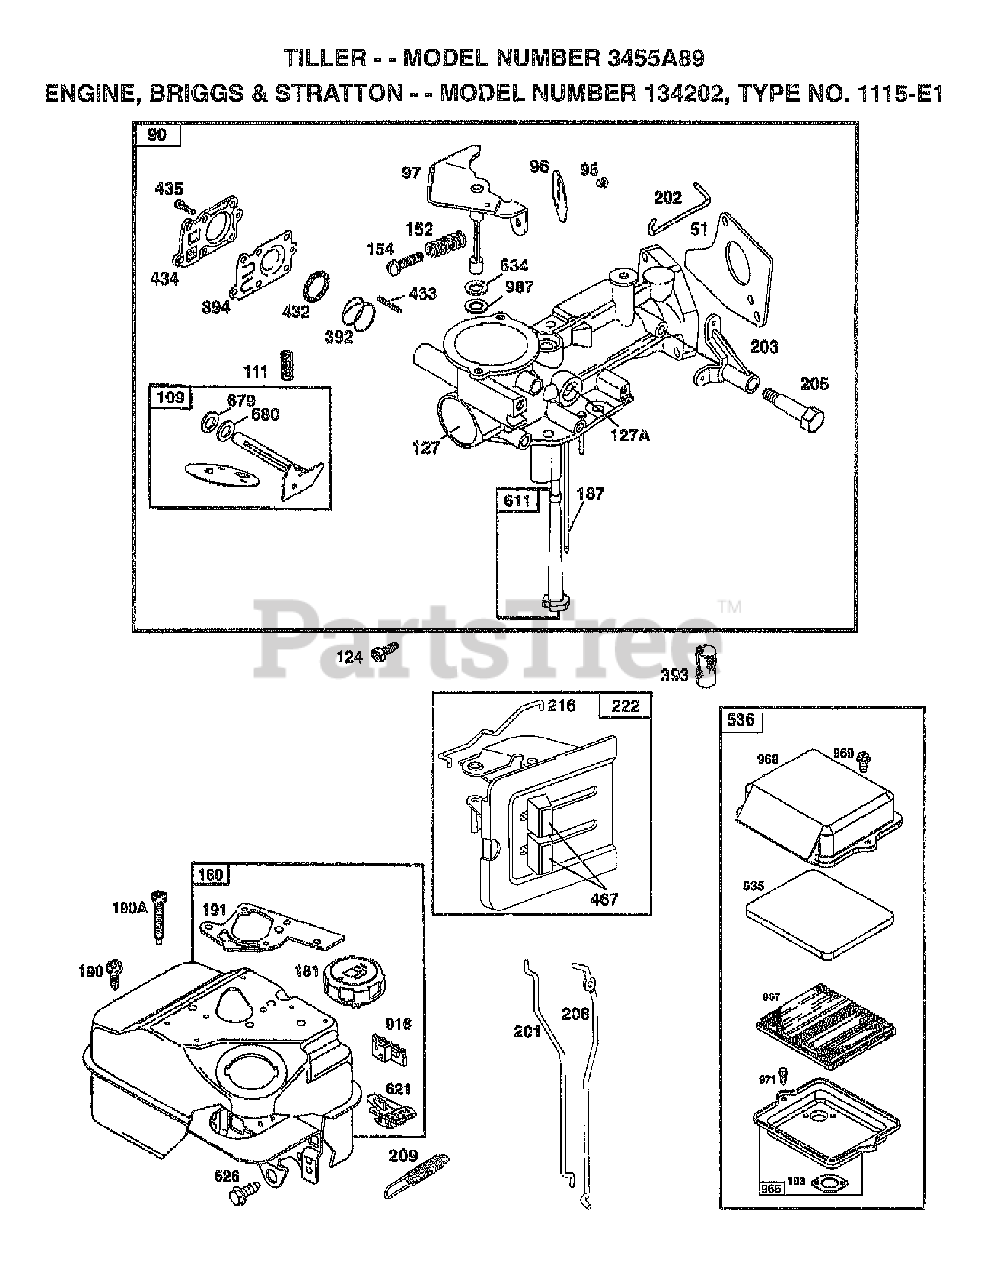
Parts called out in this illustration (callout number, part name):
1	Poulan TBD
2	Poulan TBD
5	Poulan TBD
8	Poulan TBD
12	Poulan TBD
14	Poulan TBD
15	Poulan TBD
16	Poulan TBD
18	Poulan TBD
19	Poulan TBD
21	Poulan TBD
21A	Poulan TBD
22A	Poulan TBD
23	Poulan TBD
25	Poulan TBD
26	Poulan TBD
29	Poulan TBD
30	Poulan TBD
46	Poulan TBD
51	Poulan TBD
55	Poulan TBD
56	Poulan TBD
58	Poulan TBD
65	Poulan TBD
73	Poulan TBD
90	Poulan TBD
97	Poulan TBD
109	Poulan TBD
121	Poulan TBD
180	Poulan TBD
181	Poulan TBD
187	Poulan TBD
190	Poulan TBD
190A	Poulan TBD
191	Poulan TBD
219	Poulan TBD
300	Poulan TBD
304	Poulan TBD
306	Poulan TBD
307	Poulan TBD
308	Poulan TBD
358	Poulan TBD
373	Poulan TBD
393	Poulan TBD
394	Poulan TBD
434	Poulan TBD
455	Poulan TBD
456	Poulan TBD
526	Poulan TBD
528	Poulan TBD
535	Poulan TBD
536	Poulan TBD
542	Poulan TBD
608	Poulan TBD
616	Poulan TBD
741	Poulan TBD
779	Poulan TBD
870	Poulan TBD
883	Poulan TBD
966	Poulan TBD
967	Poulan TBD
968	Poulan TBD
971	Poulan TBD
978	Poulan TBD
979	Poulan TBD
982	Poulan TBD
995	Poulan TBD
1036	Poulan TBD
1095	Poulan TBD
2500	Poulan TBD
